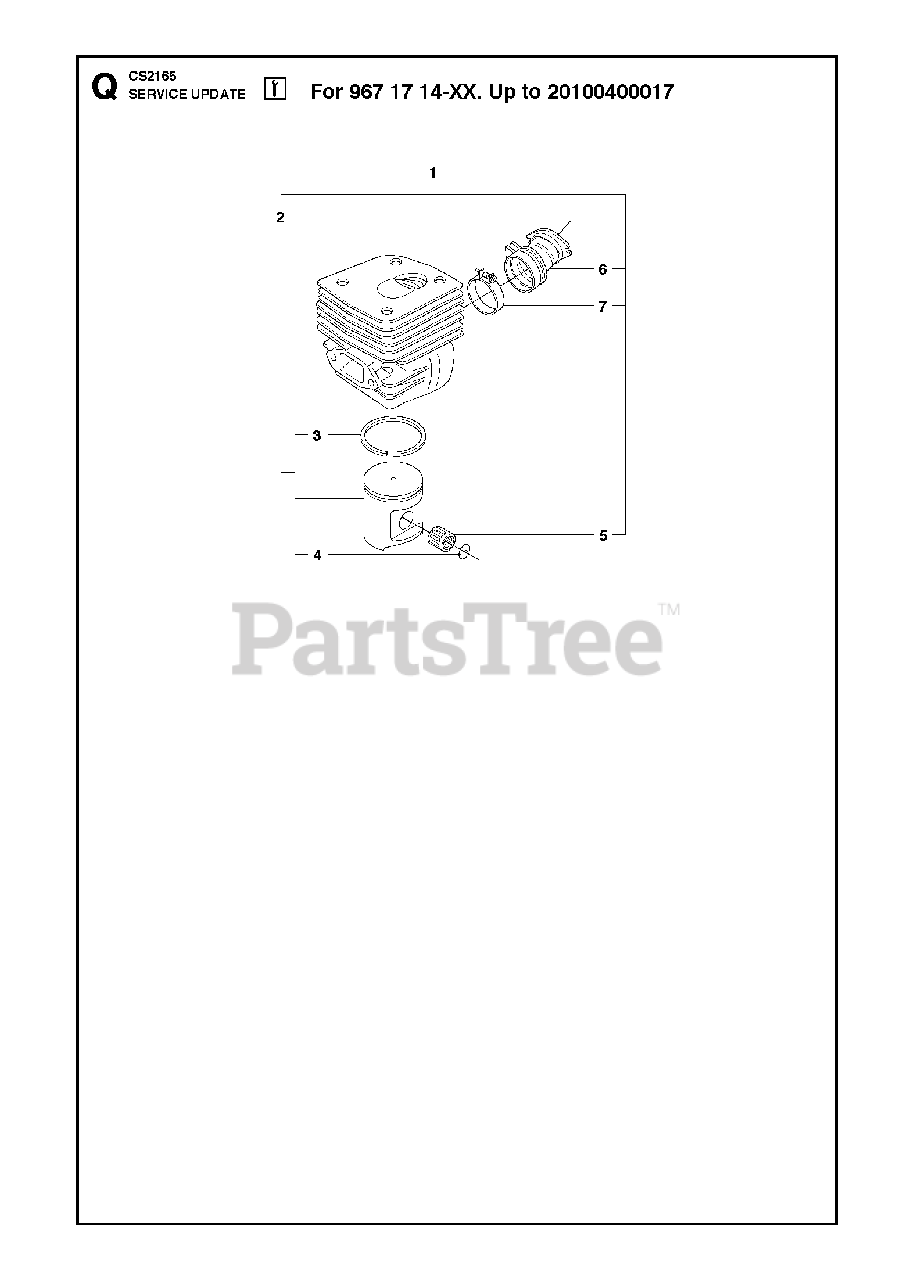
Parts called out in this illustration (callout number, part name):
1	CYLINDER
2	PISTON CPL 48 MM
3	PISTON RING
5	SUPPORT BUSHING
6	INTAKE PIPE - EPA
7	CLAMP
